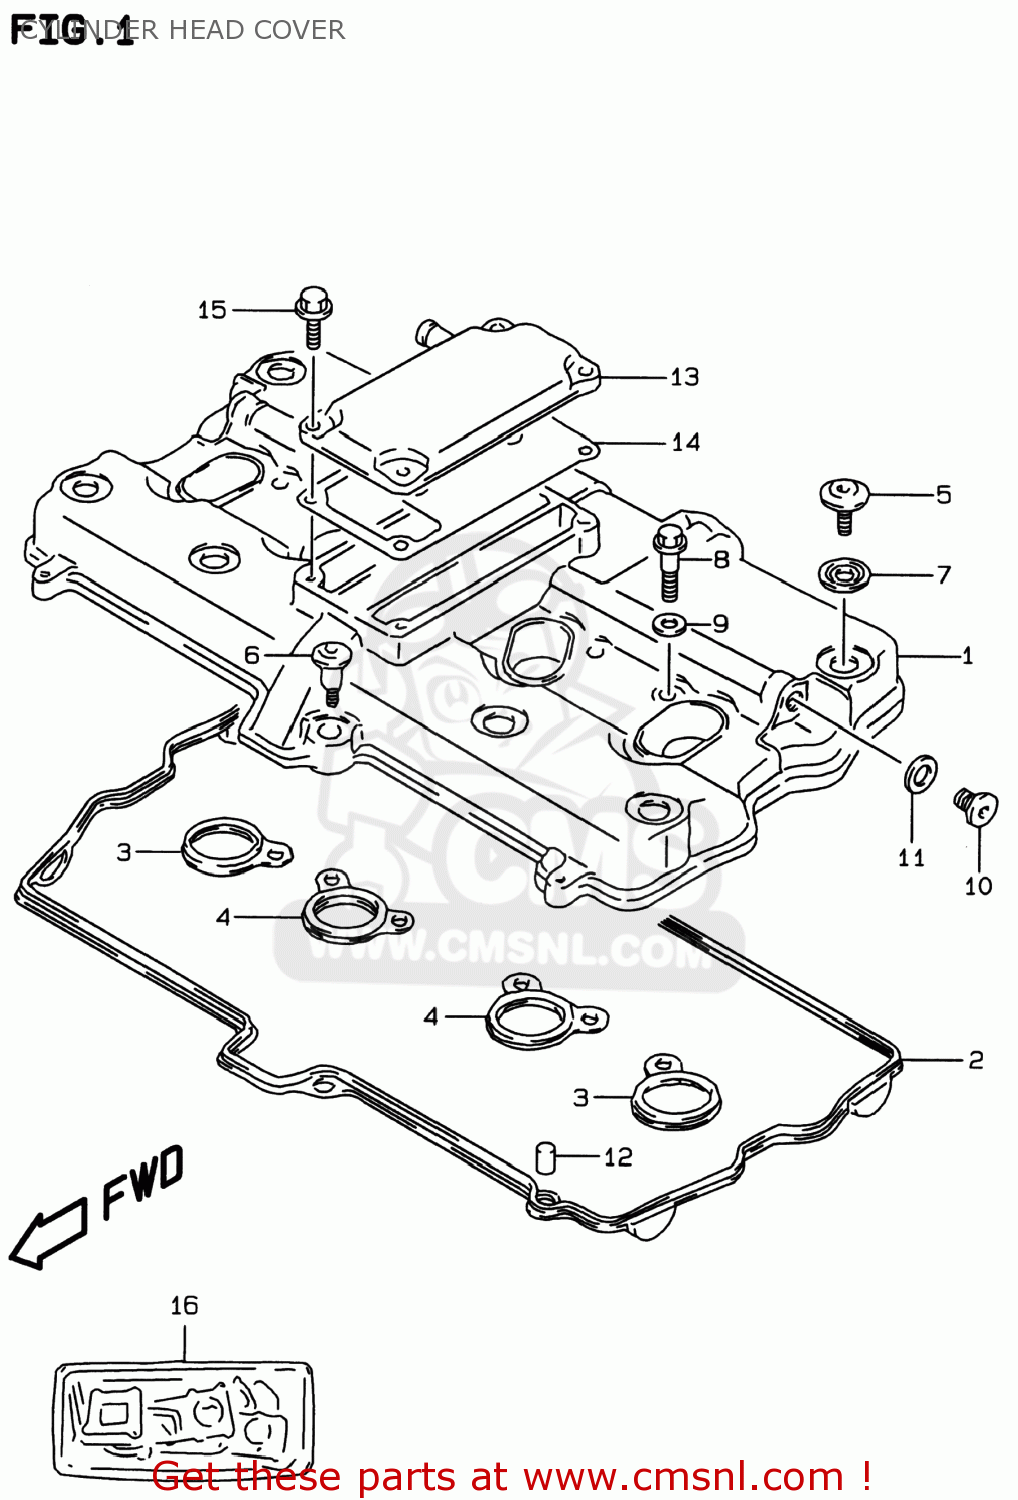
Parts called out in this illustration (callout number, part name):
1	COVER,CYLINDER HEAD
2	GASKET,CYLINDER HEAD COVER (NAS)
3	GASKET,HEAD COVER NO.2 (NAS)
4	GASKET,HEAD COVER NO.3 (NAS)
5	BOLT(7X17.5)
6	BOLT(7X31)
7	WASHER(10.6X25.5X2.3)
8	BOLT,UNION 8X35
9	GASKET 8.2X14X1 (NAS)
10	PLUG(L:12)
11	GASKET(12.1X16.2X3.7) (NAS)
12	PIN
13	COVER,BREATHER
14	GASKET,BREATHER COVER
15	BOLT
16	GASKET SET (NAS)
